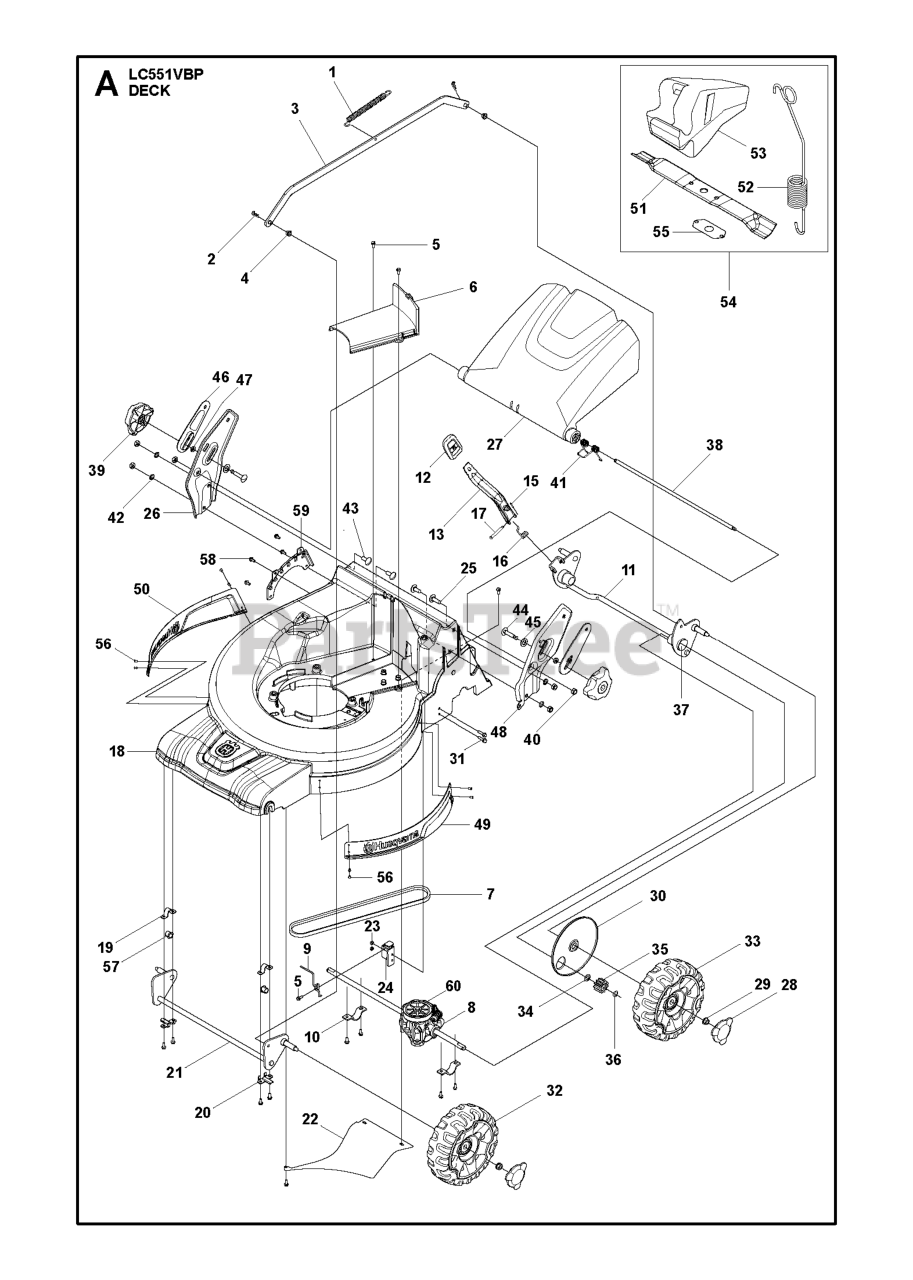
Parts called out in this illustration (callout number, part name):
7	Belts
31	SCREW M6S 5X20
37	Ball Bearings
40	LOCKNUT M8
41	SPRING 51 CAST
42	WASHER BRB 8.4X17
47	NUT ML6M M8
56	Rivet
60	TRANSMISSIONS
